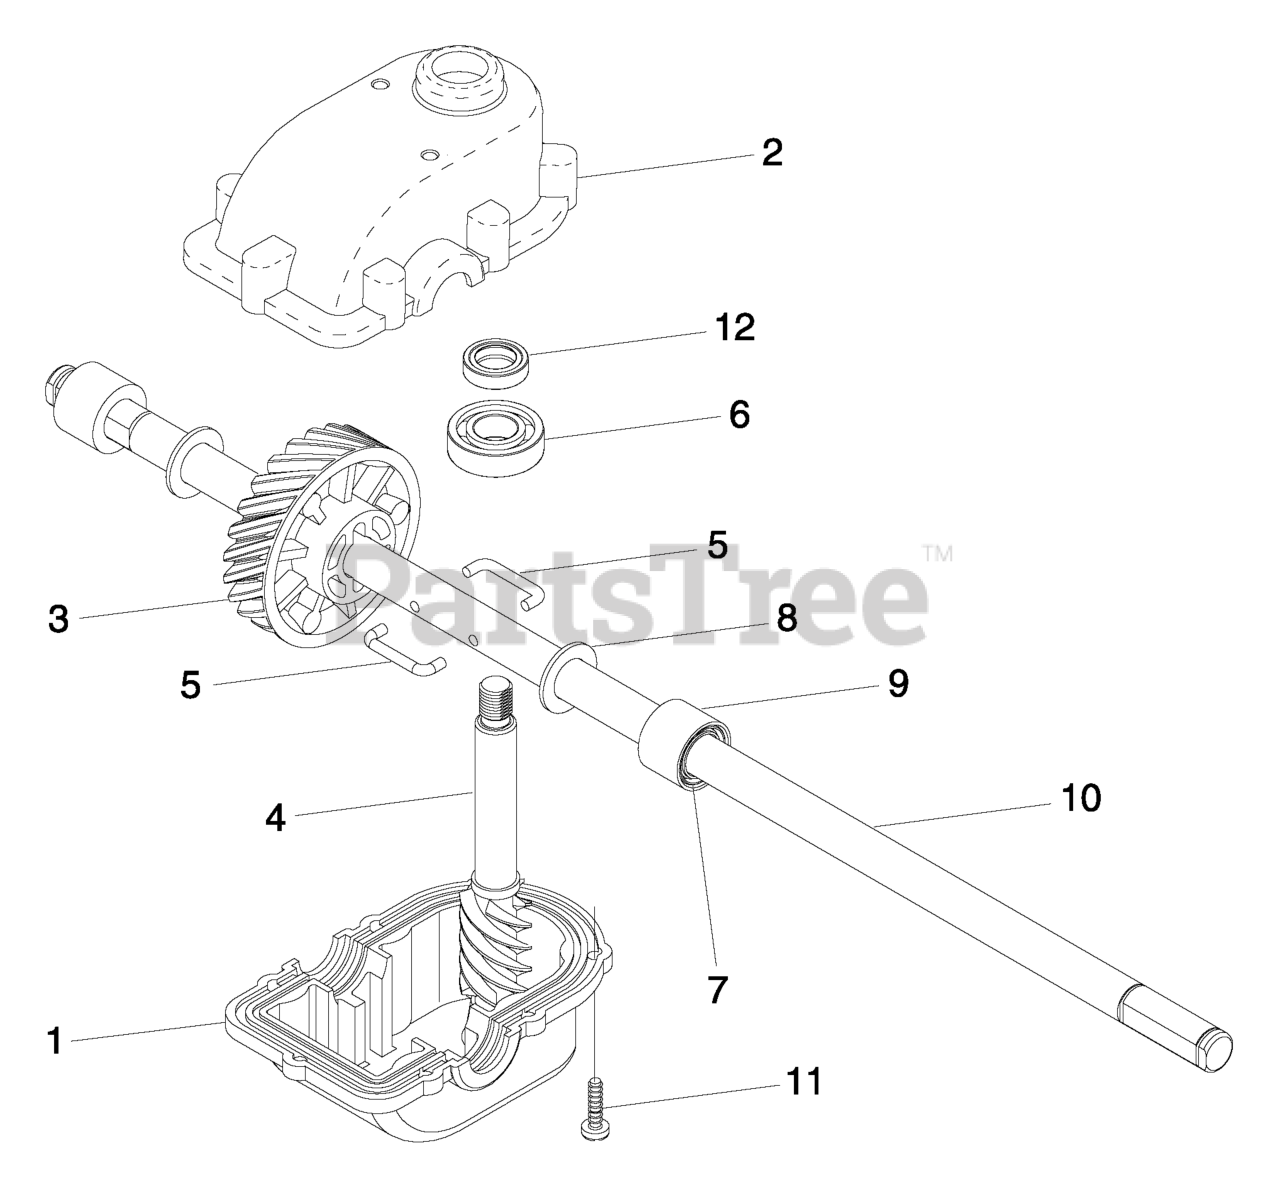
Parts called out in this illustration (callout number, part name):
1	CASE, LOWER
2	GEARCASE.HOUSING
3	GEAR.24.TOOTH.WALK.MOWER
5	WIRE, FORMED (15966)
7	SEAL.OUTPUT.SHAFT
10	SHAFT OUTPUT
12	SEAL INPUT SHAFT
